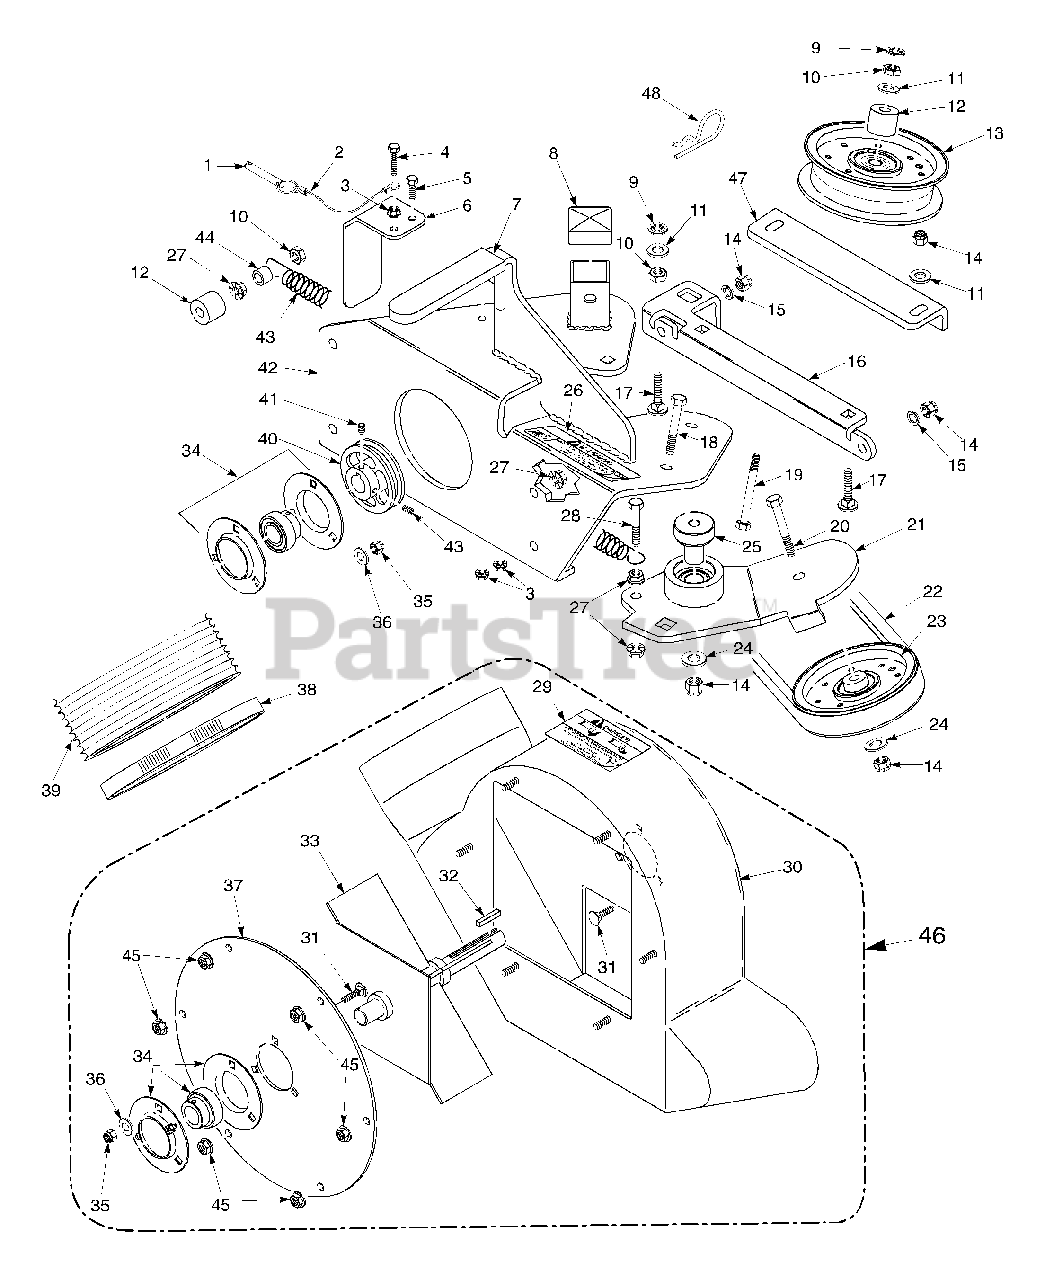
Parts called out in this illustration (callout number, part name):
1	Pin, Ring 2-1/4" Long
2	Lanyard, Deck Height Pin
3	Nut, Serr. Flange 1/4-20
4	Bolt, Hex Head 1/4-20 x 1-1/4"
5	Bolt, Hex Head 1/4-20 x 3/4"
6	Belt Cover, Rear
7	Grip, Blower Lever
8	Cap, Square
9	Nut, Push On 3/8 Thread
10	Lock Nut, 3/8-16
11	Flatwasher, 3/8-.391 x .938 x .105
12	Spacer
13	Pulley, Idler 4" Dia.
14	Nut, Elastic Stop 3/8-16
15	Lockwasher, 3/8-16
16	Plate, Catch Mounting
17	Bolt, Carr. 3/8-16 x 1-1/2"
18	Bolt, Hex Head 3/8-16 x 2-1/4"
19	Bolt, Hex Head 3/8-16 x 3-1/4"
20	Bolt, Hex Head 3/8-16 x 2"
21	Idler Arm Weldment
22	Belt, GC-STC
23	Pulley, 3" O.D.
24	Washer, 3/8 Hardened
25	Pivot, Idler
26	Decal, Belt Cover
27	Nut, Serr. Flange 3/8-16
28	Bolt, Hex Head 3/8-16 x 1-1/2 Gr. 8
29	Decal, Danger
30	Blower Housing Weldment,
31	Bolt, Carr. 5/16-18 x 3/4" Gr. 5
32	Key, 1/4 x 1/4 x 1-1/2"
33	Fan Weldment
34	Bearing with Locking Collar
35	Nut, Elastic Stop 5/16-18
36	Flatwasher, 5/16-.344 x .688 x .065
37	Cover, Blower Housing
38	Clamp, 6-1/2" Max Dia.
39	Hose, 6" Dia.
40	Pulley, 4-3/4" O.D. - 1" Bore
41	Set Screw, 5/16-18 x 3/8"
42	Frame Weldment, Blower Mount
43	Spring, Main Drive
44	Spacer
45	Nut, Serr. Flange 5/16-18
46	Blower Housing Assembly
47	Plate, Blower Catch
48	Hair Pin Cotter, .243 x 4"
